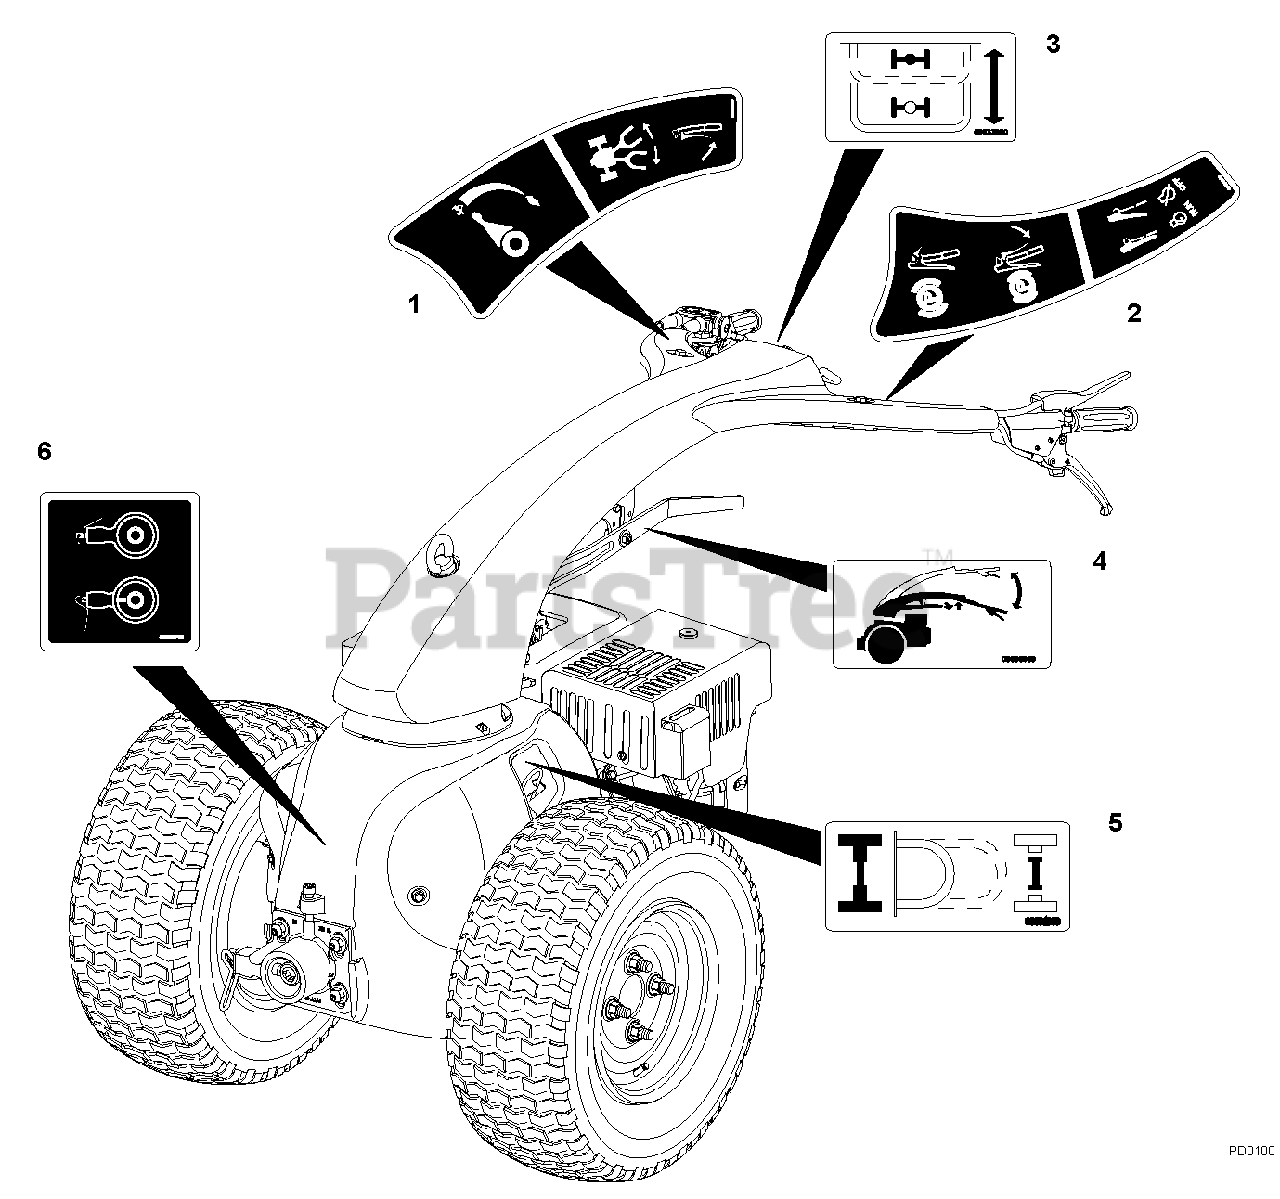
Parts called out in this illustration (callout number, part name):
1	Decal, Handlebar SwivelL/Throttle Control
2	Decal, Park Switch/OPC Control
3	Decal, Differential Lock
4	Decal, Handle Adjustment
5	Decal, Drive Disengagement
6	Decal, Attachment Lock
